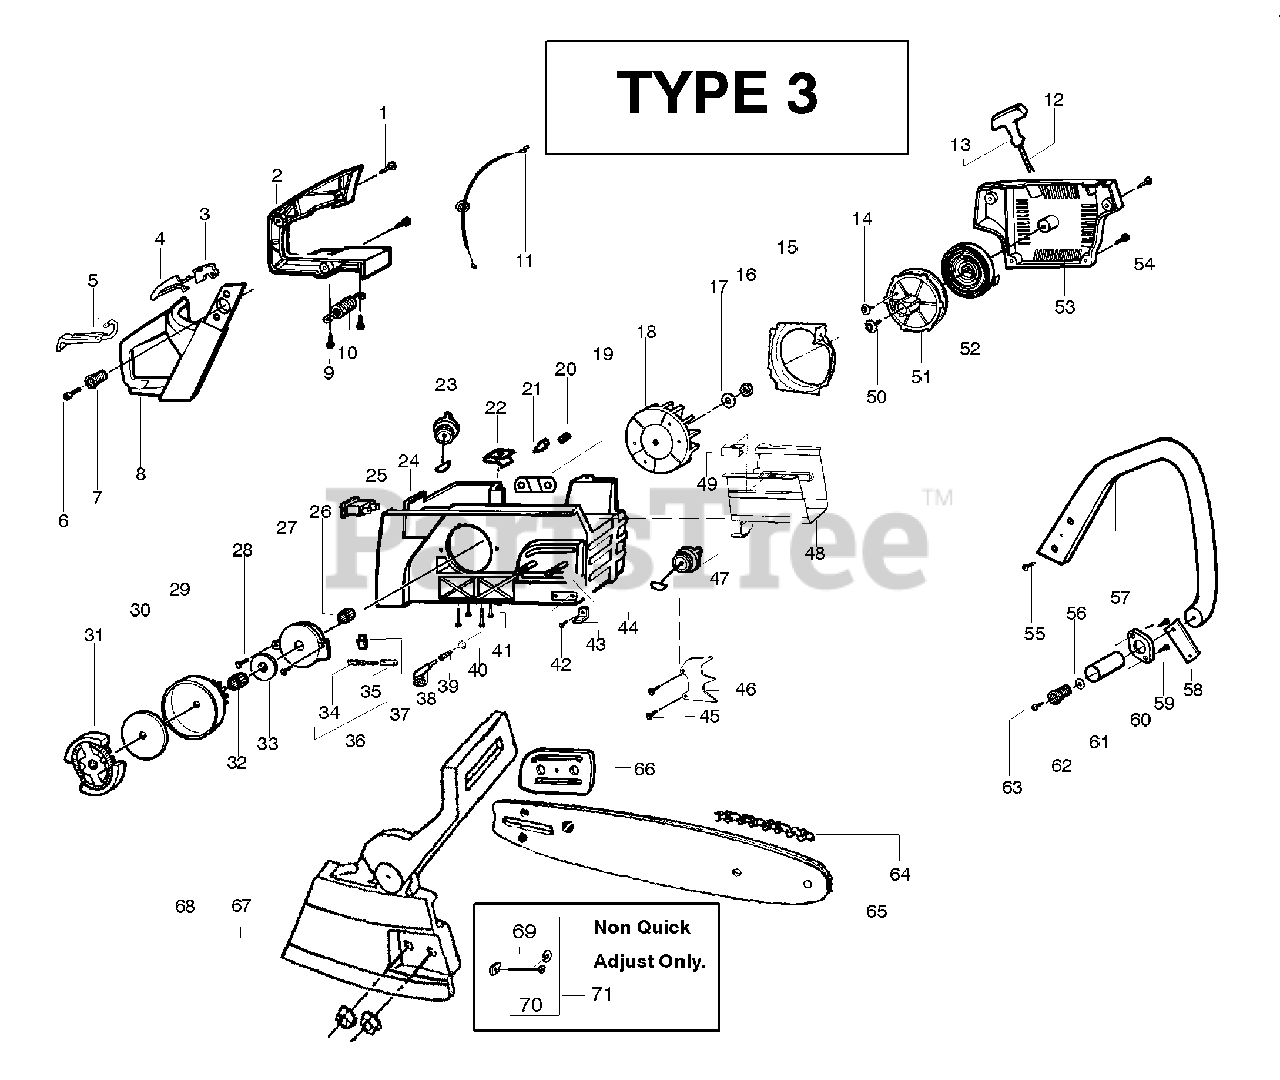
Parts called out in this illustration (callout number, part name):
2	Cover-Handle
3	Trigger-Throttle
4	Lockout-Throttle
5	Lever-Choke
7	Spring-Isolator
8	Handle-Rear
10	Spring-Isolator
11	Assy-Throttle Cable
12	Kit-Rope
13	Handle-Starter
15	Plate-Baffle Fan
16	Nut-Flywheel
17	Washer-Flywheel
18	Assy-Flywheel
19	Plate-Support
20	Plug-Vent
21	Valve-Check
22	Nut-Speed
23	Assy-Fuel Cap
24	Assy-Chassis
25	Kit-Switch
26	Worm-Oil Pump
27	Hsg.-Oil Pump
29	Kit-Clutch Drum
30	Washer-Clutch
31	Assy-Clutch
32	Bearing-Clutch
33	Washer-Thrust
34	Assy-Plunger/Gear
35	Barrel-Oil Pump
36	Assy-Oil Pump
37	Seal-Oil
38	Pickup-Oil
39	Filter-Oil
40	Plug-Oil Filter
43	Chain Catcher
44	Bar Bolt
45	Screw
46	Kit-Spike Assy
47	Assy-Oil Cap
48	Shield-Heat
49	Clip-"U"
51	Kit-Starter Pulley
52	Spring-Recoil
53	Housing-Fan
57	Handle-Front
58	Front Strap-AV
59	Screw-Plate
60	Plate-Isolator
61	Spring Sleeve-AV
62	Spring-Isolator
64	Chain" 16"
64	Chain" 20"
65	Bar 16" Standard
65	Bar 20" Quick Adjust
65	Bar 20" Pro Lam Quick Adj.
66	Bar Plate
67	Assy-ChainBrake
68	Nut-Bar Mounting
69	Retainer
70	Pin-Bar Adjust
71	Kit-Bar Adjust
